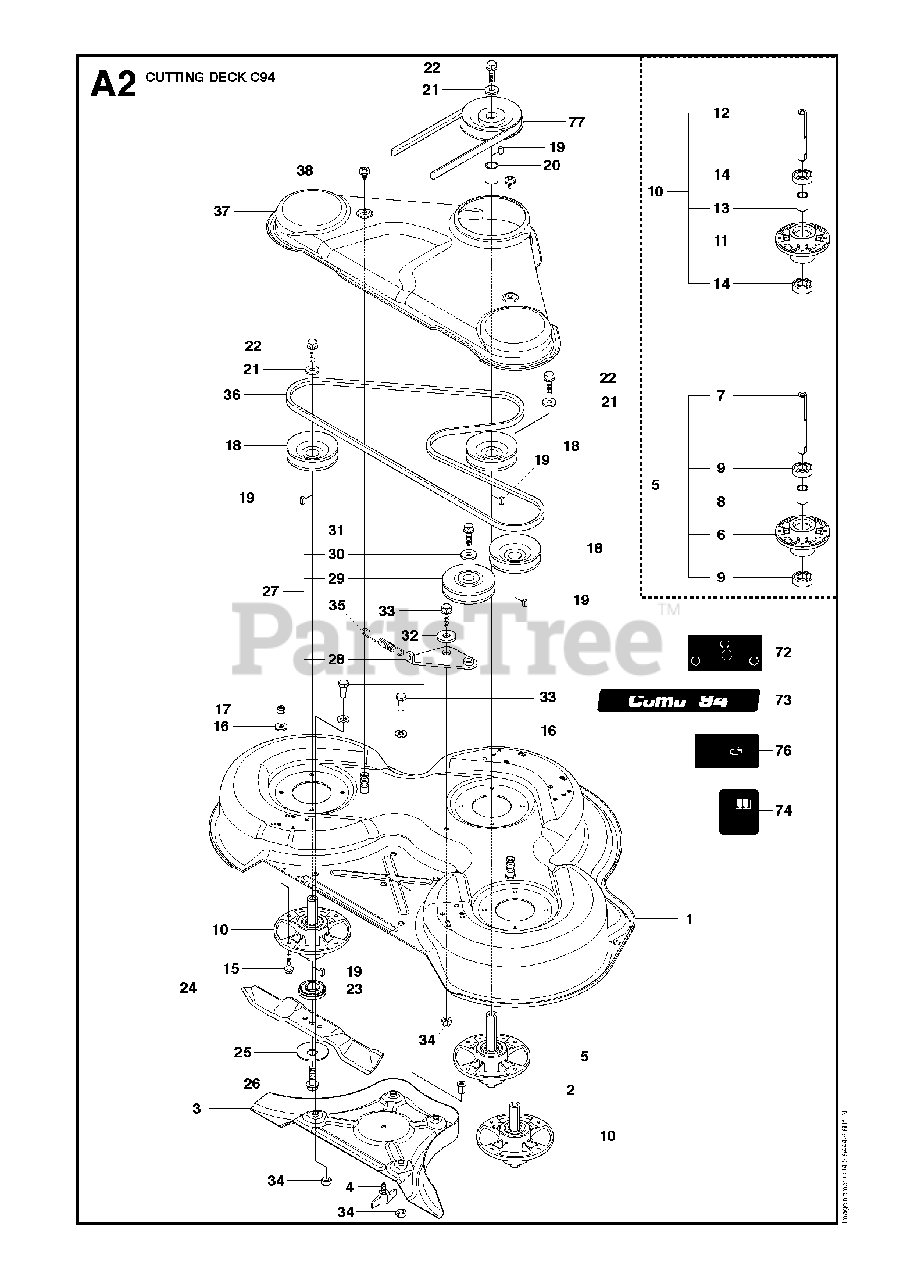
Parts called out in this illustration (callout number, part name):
1	CUTTING DECK CT94 GREY WITH P
3	PLUG C93 & C94
5	BLADE HOUSING ASSY
6	BEARING HOUSING
7	SHAFT
8	SPACING SLEEVE
9	BEARING
10	BLADE HOUSING ASSY
11	BEARING HOUSING
12	SHAFT
13	SPACING SLEEVE
14	BEARING
16	WASHER BRB 8.4X17
17	LOCKNUT M8
24	BLADE
25	WASHER
27	BELT TENSIONER ASSY
28	BELT TENSIONING ARM
29	PULLEY
30	SPACER
31	BOLT
32	WASHER
34	LOCKNUT M8
37	BELT COVER C93 & C94 GREY
